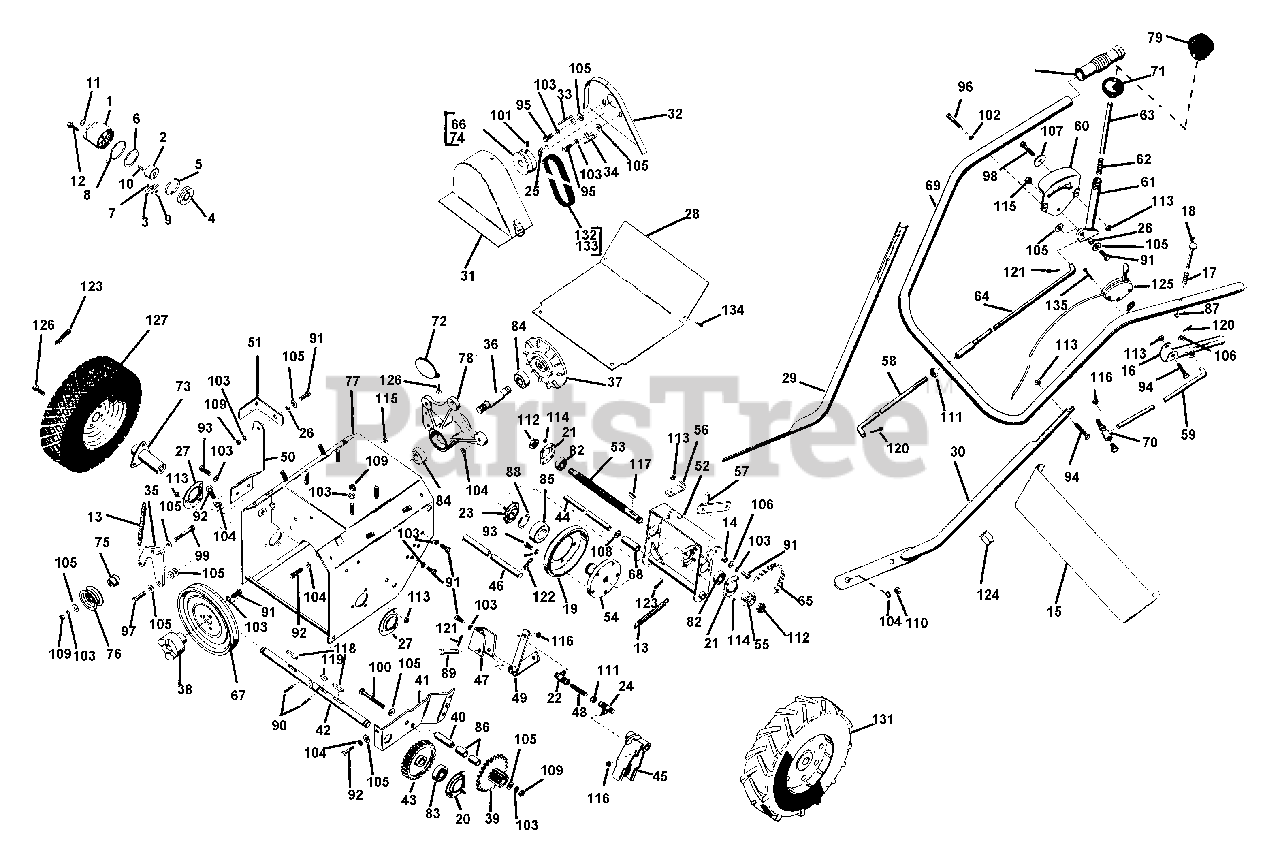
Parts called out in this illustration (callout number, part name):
1	RATCHET WHEEL HUB
2	PAWL DRIVE HUB
5	FRICTION SPRING
6	RETAIN WASH
7	WAVE WASHER .406X.750X.063FH
8	O-RING 3.85X4.27X.210
9	PIN-ROLL .188X.88
10	PIN-GRV .375X1.00 TP C
11	WSHR-FL-STL .531X1.062X.095 PL
12	BRG-CUP 2.441X.562
13	SPRING
14	SPACER BUSHING .5 X .32 X .163
15	HANDLE BAR PANEL
16	CLUTCH HANDLE
17	SG-COMP ??X.44X?? WLD 10
18	CLUTCH LOCK PIN
19	FRICTION DISC
20	BEARING FLANGE
21	BEARING FLANGE
22	SNAP IN BALL JOINT
23	BEARING FLANGE
24	BALL JOINT
26	SPACER BUSHING .5 X .32 X .21
27	BEARING FLANGE
28	BOTTOM COV
29	R H LOWER HANDLE BAR
30	L H LOWER HANDLE BAR
31	OUTER BELT GUARD
32	INNER BELT GUARD
33	R H BELT FINGER
34	L H BELT FINGER
35	IDLER ARM
36	SPINDLE
37	DRIVE PLATE
38	JAW COUPLING
39	PINION & SPROCKET
40	PINION STUB SHAFT
41	SUPPORT BRACKET
42	AXLE SHFT
43	SPUR GEAR, FELLOWS 35T .750 ID
44	BRACKET PIN
45	SLIDING FORK
46	FORK SHAFT
47	LEVER BRACKET
48	CONNECTING LINK
49	TRANSFER LEVER
50	CLTCH BRCKT
51	CLUTCH LEVER
52	DISC BRCKT
53	SPLINED SHFT
54	FRICTION DISC HUB
56	NEUTRAL CATCH
57	THROWOUT LEVER
58	LOWER SHIFT ROD
59	CLTCH ROD
60	SHIFT QUADRANT
61	SHIFT HANDLE
62	SPRING
63	RELEASE ROD
64	SHIFT ROD
65	ROLLER CHAIN
66	ENGINE SHEAVE
69	UPPER HANDLE BAR
70	BALL JOINT
71	SHIFT BALL
72	COVER
73	WHEEL HUB
74	ENGINE SHEAVE
75	SPACER BUSHING
77	TRACTOR FRAME
78	BEARING HOUSING
79	SHIFT KNOB BOOT
80	6 HP CARB COVER
81	3 1/2 HP CARB COVER - ALL
82	BRG-BALL .625X1.375X.44
83	BRG-BALL .750X1.750X.50
84	BRG-BALL .750X1.750X.50
85	BRG-BALL 1.25X2.18X.63
86	BSHG-FLG .625X.750X.500X.875BR
87	RG-RTNG-EXT .250X.031
88	RG-RTNG-EXT 1.250X.050
89	CLEVIS PIN
90	PIN-ROLL .250X1.25
91	BLT-HEX .31-18X.63 PL GR 2
92	BLT-HEX .31-18X.63 PL GR 2
93	BLT-HEX .31-18X1.00 PL GR 2
94	BLT-HEX .38-16X1.25 PL GR 2
95	BLT-HEX .38-16X1.25 PL GR 2
96	BLT-HEX .38-16X1.25 PL GR 2
97	BLT-HEX .38-16X1.50 PL GR2
98	BLT-HEX .44-14X1.25 PL GR2
99	BLT-HEX .44-14X1.25 PL GR2
100	BLT-HEX .44-14X1.25 PL GR2
101	SCR-SET .38-16X.50 SKHCUP OH
102	WSHR-LK .250X.077 HVY PL
103	WSHR-LK .312X.097 PL HVY
104	WSHR-LK .375X.115 HVY PL
105	WSHR-FL-STL .38X.875X.083 PL
106	BRG-CUP1.980X.420
107	WSHR-FL-STL .531X1.062X.095 PL
108	BRG-NEEDLE .625X.812X.50
109	NUT-JAM .375-16 PL
110	NUT-JAM .375-16 PL
111	NUT-HEX .312-24 PL
112	NUT-LK-CTR .625-18 PL
113	NUT-LK-CTR .250-20 PL
114	NUT-LK TOP 10-24 PL
115	NUT-LK .312-18 GR A PL
116	NUT-LK-CTR .312-24 PL
117	KEY-WDRF .188X.75X.313 SAE 9
118	KEY-WDRF .188X.875X.375 SAE11
119	KEY-WDRF .188X.875X.375 SAE11
120	PIN-COTR .09X.75 PL
121	PIN-COTR .12X1.0 PL
122	PIN-COTR .09X.75 PL
123	PIN-COTR .09X.75 PL
124	THROTTLE CONTROL
125	THROTTLE CONTROL
126	BRG-CUP 2.441X.562
127	T/WHL ASSY
128	TIRE 4.10/3.50X6 2PLY
129	TUBE
130	WHL 6 IN O.D.
131	WHL
132	V-BELT, SAE 380-RAW EDGE
133	V-BELT, 4L-WRAPPED
134	SCR-TAP 10-12X.50 CRPH PL A
135	SCR-TAP 10-16X1.0 SLHP PL AB
136	GRIP
